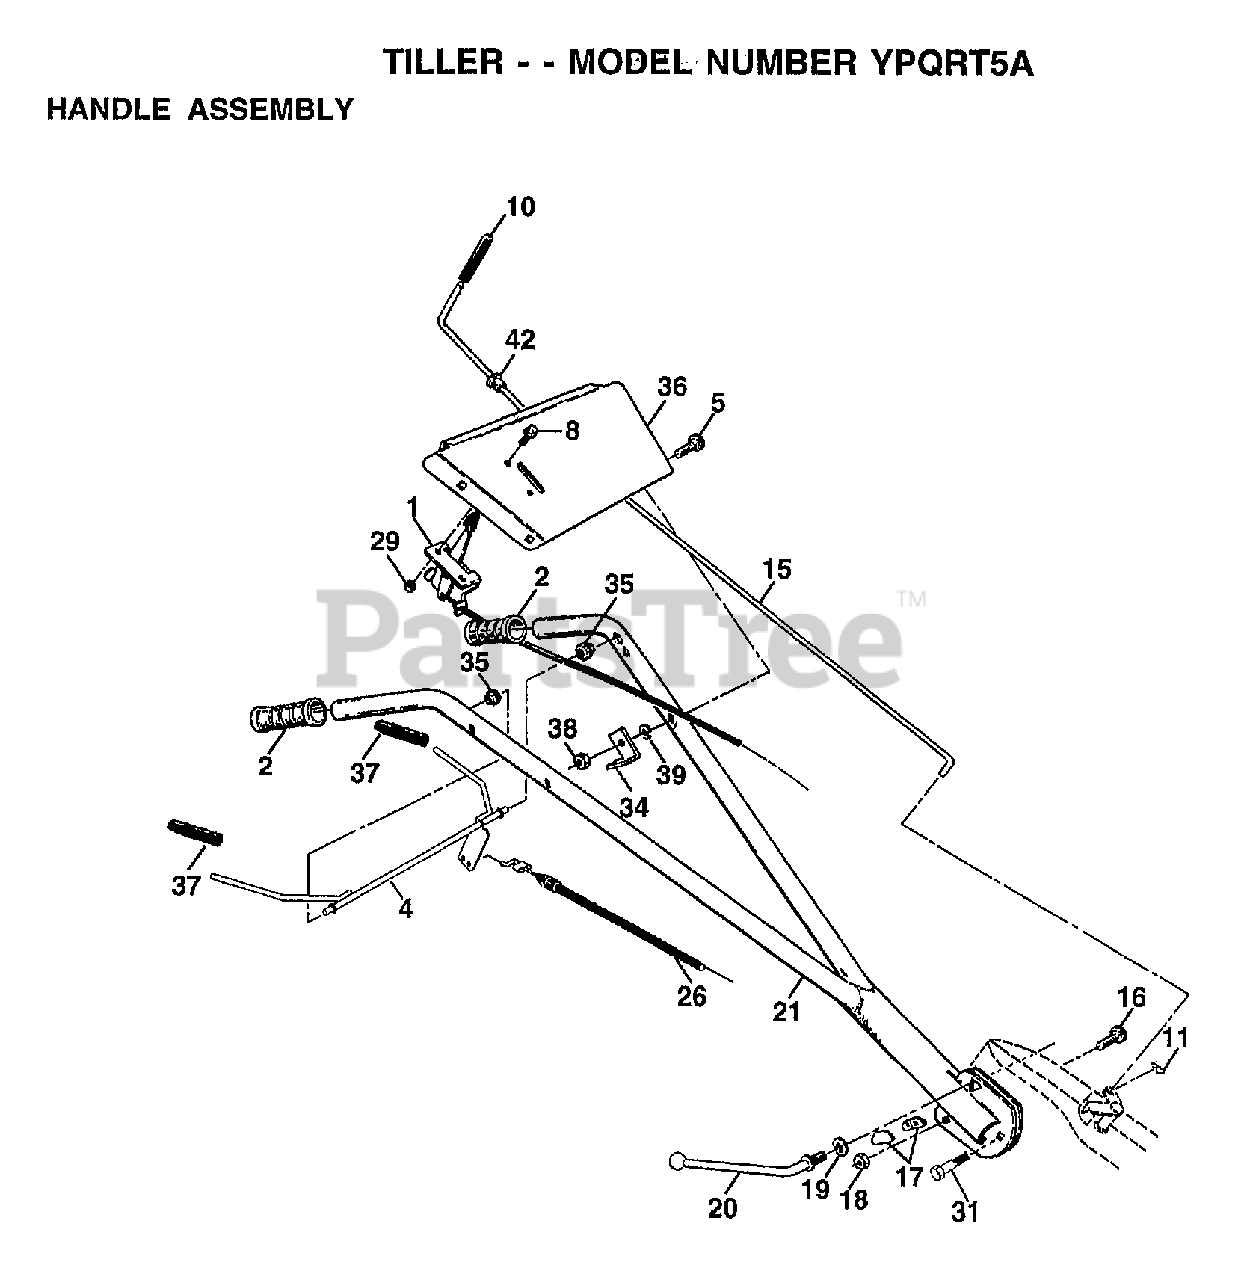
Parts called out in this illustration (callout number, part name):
1	"CONT,THROTTLE"
2	"GRIP,HANDLE"
4	BAR CONTROL
5	BOLT CARRIAGE CRT
8	SCREW.PNHD.10-24
10	GRIP TI
11	RETAINER M
15	ROD SHIFT CRT
16	BOLT D
17	LOCK CRT
18	LOCKNUT
19	WASHER CRT
20	LEVER LOCK CRT
26	"CABLE, CLUTCH"
31	BOLT PIVOT
34	BRACKET.CLUTCH.CA
35	GROMMET.HANDLE.V-
37	GRIP BAR CRT
38	NUT
39	LOCKWASHER
42	BUSHING
